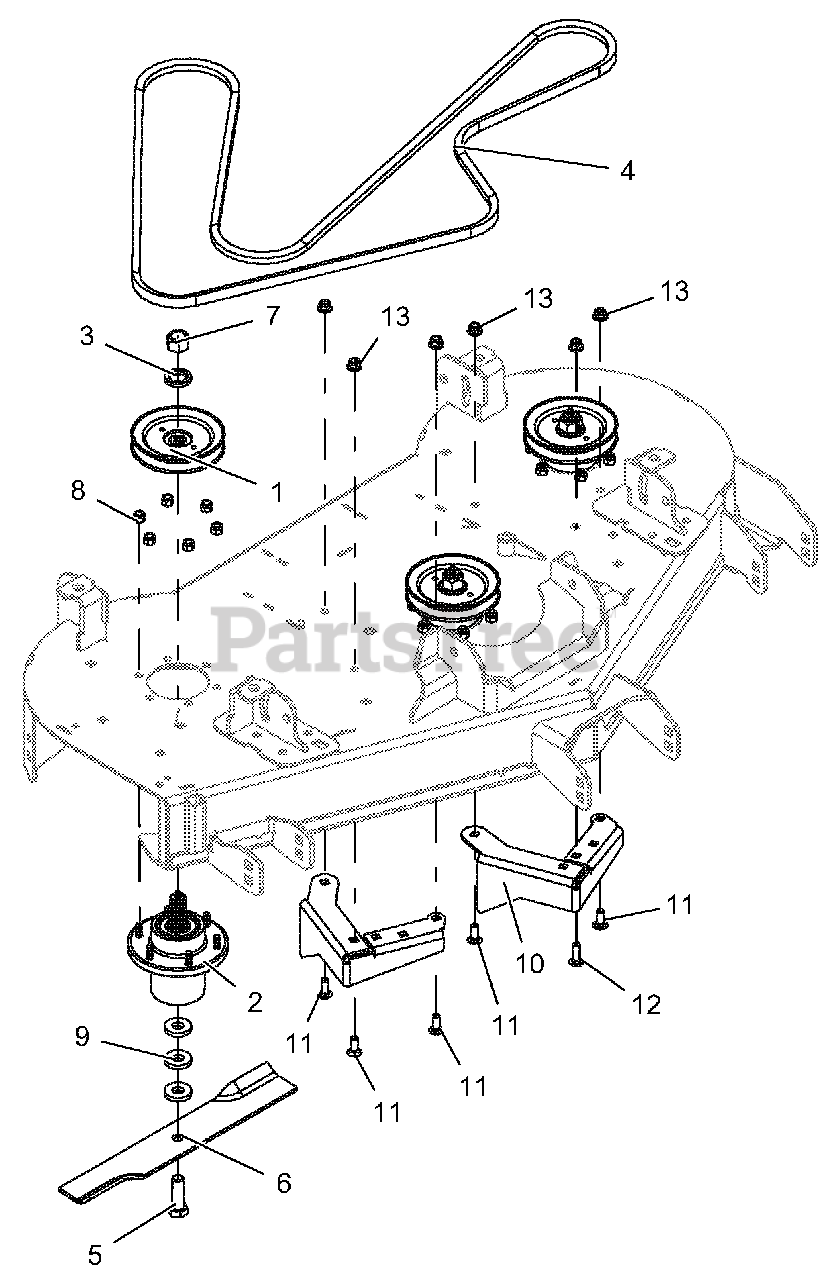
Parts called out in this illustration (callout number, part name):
1	PULLEY, SPINDLE .76 HUB - BLACK
2	ASSY, SPINDLE HOUSING
3	SPCR, 1.005 x 1.505 x .250 PM
4	V-Belt, 5L-WRAPPED CLUTCHING
5	BLT-HEX .62-11 x 2.00 GR8 YWZC
6	BLADE, 16.50 LO-LIFT
7	LOCKNUT, 3/4-16 CROWN GR5 Y
8	NUT-LK-NYL .38-16 YWZC
9	WSHR-FL-STL .630 x 1.50 x .25 YWZC
10	DEFLECTOR, DIRECTION
11	BLT-RDHDSQNK .38-16 x 1.00 G5 YWZC
12	BLT-RDHDSQNK .38-16 x 1.25 G5 YWZC
13	NUT-LK-NYL-FLG .38-16 YWZC
